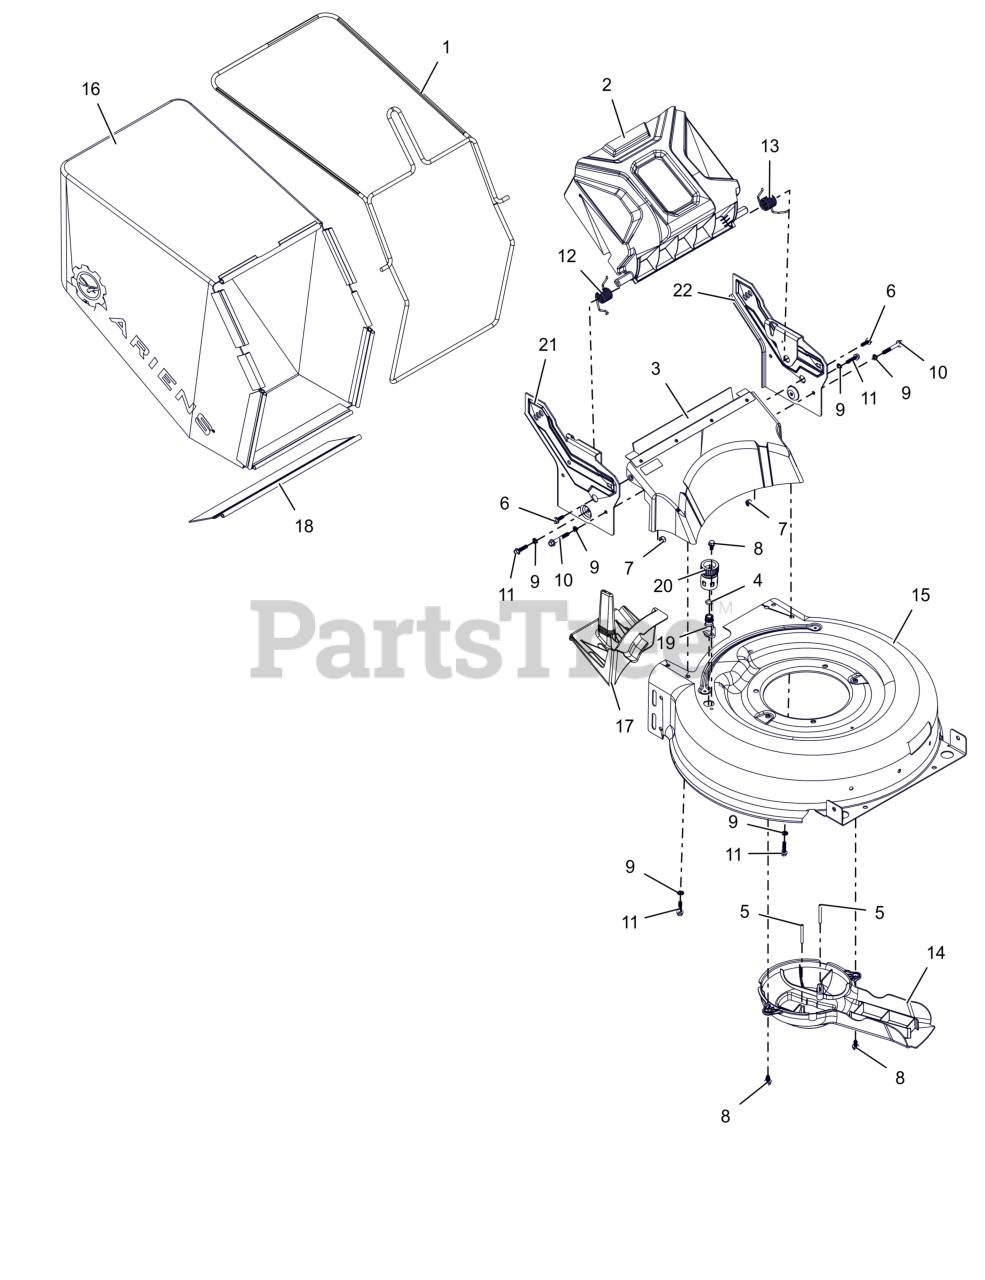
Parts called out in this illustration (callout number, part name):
1	WLDMT, BAG FRAME (ORANGE)
2	ASM, REAR DOOR
3	ASM, REAR COVER-FWD
4	O-RING, OD .625 ID .425
5	PIN, .188 X 1.750
6	SCR, HI-LO HWH 1/4-15 X .750
7	NUT, NYLOC 1/4-20
8	SCR, 1/4-20X.500, THREAD FORMING
9	WSHR-LK-EXT, .256X.510X.028
10	BLT, HEX 1/4-20 X 1.75 GR5
11	SCR, HI-LO HWH 1/4-15 X 1.00
12	SPRG, TORSION - DOOR LH
13	SPRG, TORSION - DOOR RH
14	COVER, FWD PULLEY
15	DECK, FWD -21 (WO PORT) (ORANGE)
16	BAG- BULB SEAL GRASS
17	PLUG, MULCH
18	GUARD, REAR DECK
19	ADAPTOR, DECK WASH OUT
20	CONNECTOR, QUICK DISCONNECT
21	BRKT, RH SIDE (BLACK)
22	BRKT, LH SIDE (BLACK)
